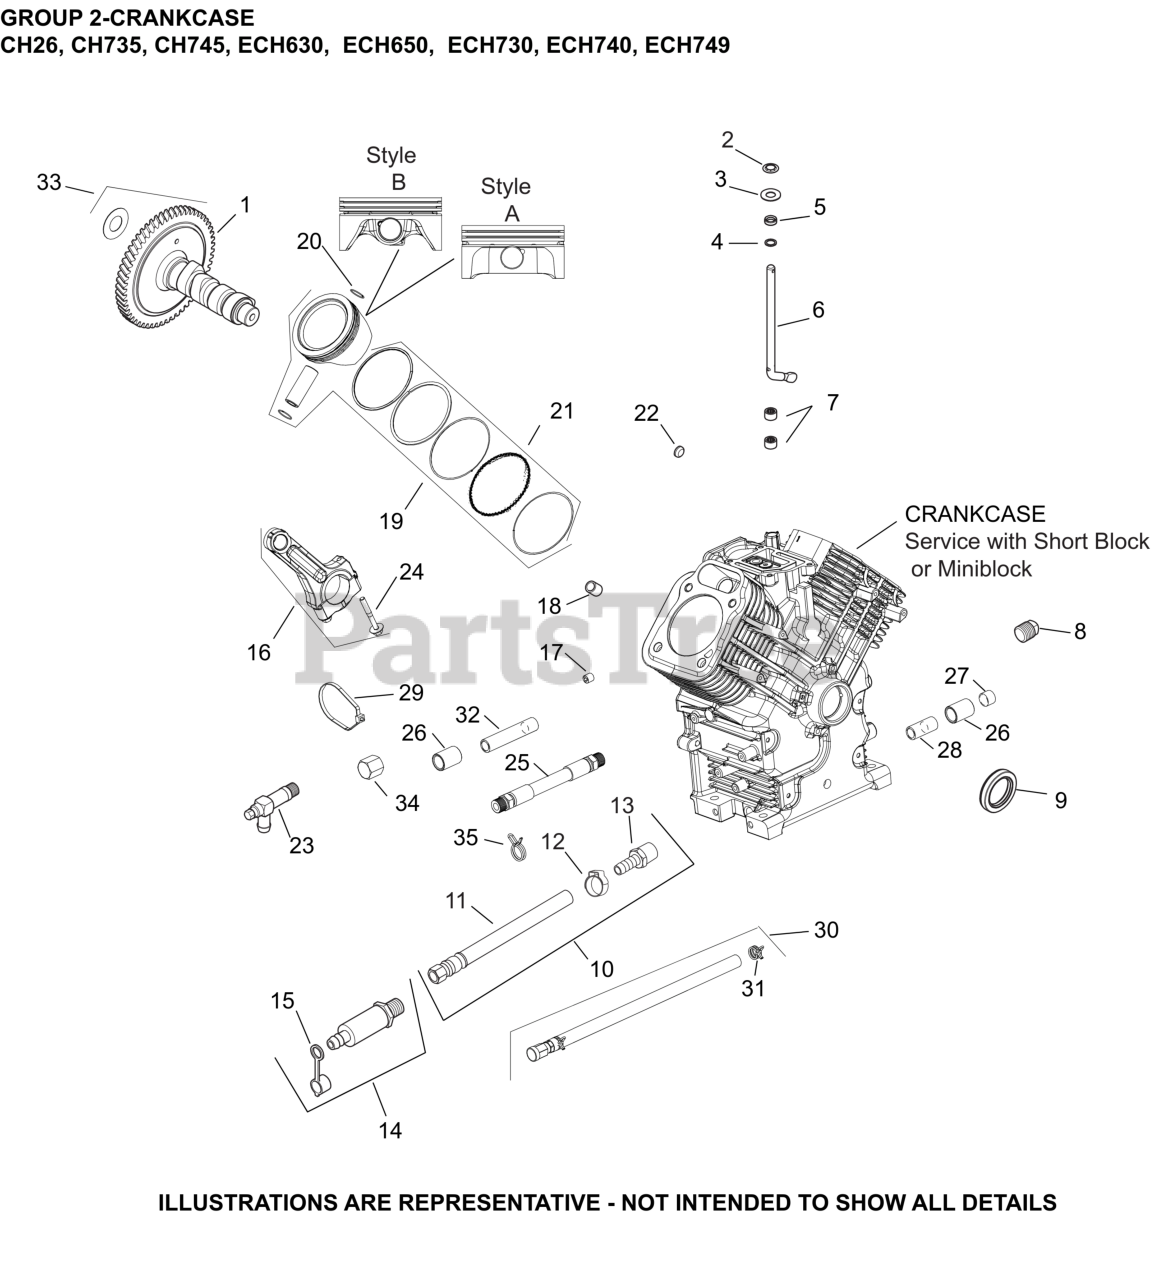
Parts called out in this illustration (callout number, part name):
1	KIT, CAMSHAFT
2	RETAINER, RING
3	WASHER, FLAT 9 MM
4	WASHER, FLAT 11/32"
5	SEAL, GOVERNOR CROSS SHAFT
6	SHAFT, GOVERNOR CROSS
8	PLUG, SQ HD PIPE 3/8"
9	SEAL, OIL (HELIX LIP)
13	FITTING, BARBED
16	ROD, ASSEMBLY CONNECTING
18	PIN, LOCATING
19	KIT, PISTON (STD) STYLE B
19	KIT, PISTON (.08) STYLE B
19	KIT, PISTON (.25) STYLE B
19	KIT, PISTON (.50) STYLE B
20	RETAINER, PISTON PIN
21	RING SET (STD) STYLE B
21	RING SET (.08) STYLE B
21	RING SET (.25) STYLE B
21	RING SET (.50) STYLE B
22	PLUG, CUP
24	KIT, ROD BOLTS-(#25086677S)
30	HOSE, OIL ASSEMBLY
